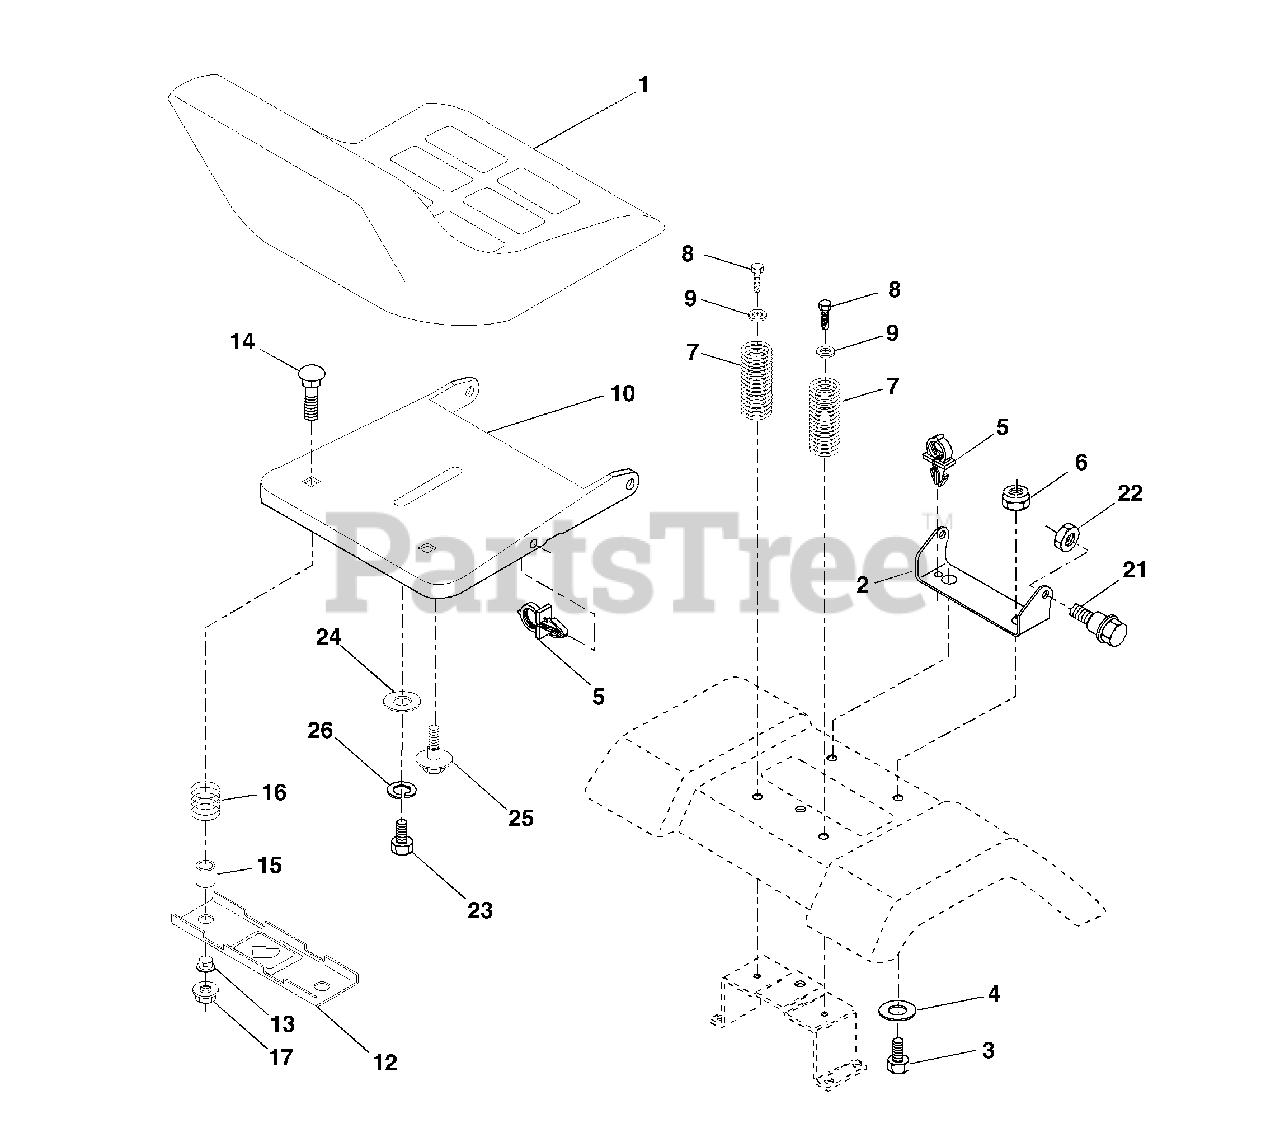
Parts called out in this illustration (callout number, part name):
1	Seat
2	Bracket Pnt Pivot Seat (blk )
3	Bolt
4	Washer 13/32 x 1 x 10 Ga
5	Clip Push-In Hinged
6	Nut
7	Spring Seat Cprsn 2 250 Blk Zi
8	Screw 3/8-16 x 1.5
9	Washer 13/32 x 1 x 14 Ga
10	Pan Pnt Seat (blk )
12	Bracket Pnt Mounting Switch
13	Bushing Snap Blk Nyl 50 Id
14	Bolt Rdhd Sht Nk 1/4-20 x 1-1/2
15	Spacer Split 28 x 96 Yel Zinc
16	Spring Cprsn 1 27 Blk Pnt
17	Nut Lock 1/4 Lge Flg Gr 5 Zinc
21	Bolt Shoulder 5/16-18 Unc Blkz-2A
22	Nut
23	Bolt Hex Black
24	Washer 17/32 x 1-3/16 x 12 Ga
25	Bolt Shoulder 5/16-18 x 62
26	Lockwasher
